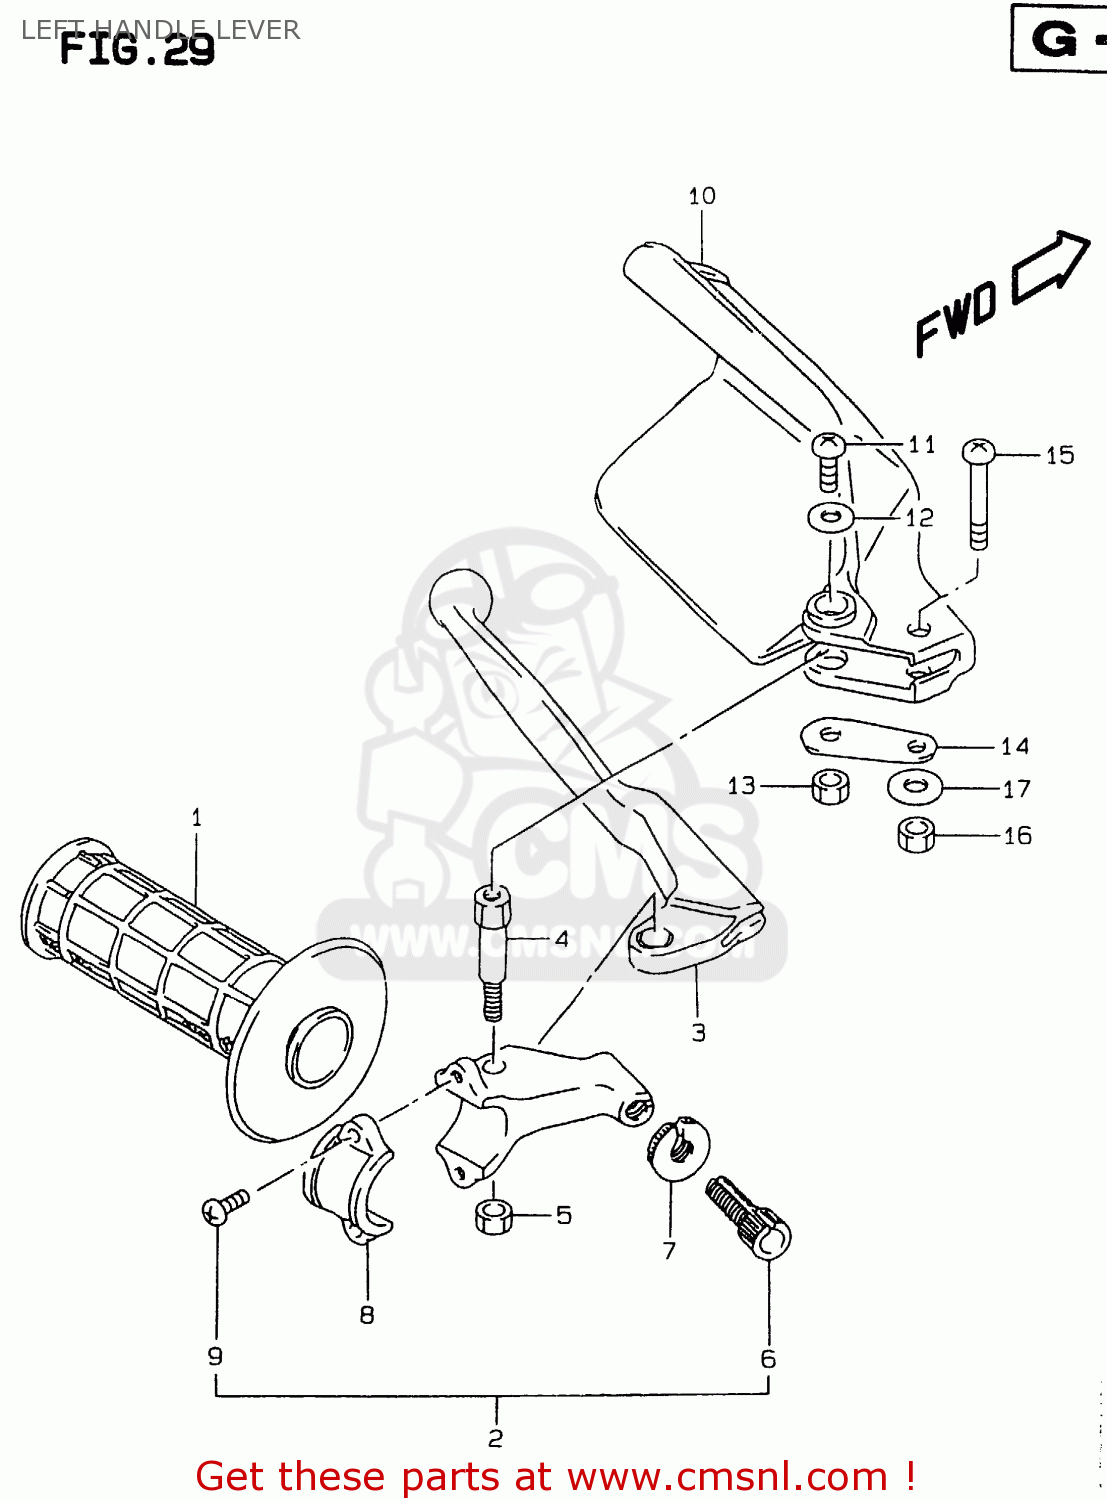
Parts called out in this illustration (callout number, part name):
1	GRIP,L
2	LEVER ASSY,CLUTCH
3	LEVER,CLUTCH
4	BOLT,LEVER SET
5	NUT 6MM
6	ADJUSTER,CABLE
7	NUT,LOCK
8	BRACKET,CLUTCH LEVER HOLDER
9	SCREW(5X14)
10	COVER,KNUCKLE,L
11	SCREW
12	WASHER(5.5X16X1.2)
13	NUT 6MM
14	PLATE,KNUCKLE COVER,L LWR
15	SCREW(6X35)
16	NUT 6MM
17	WASHER(6.5X16X1.6)
